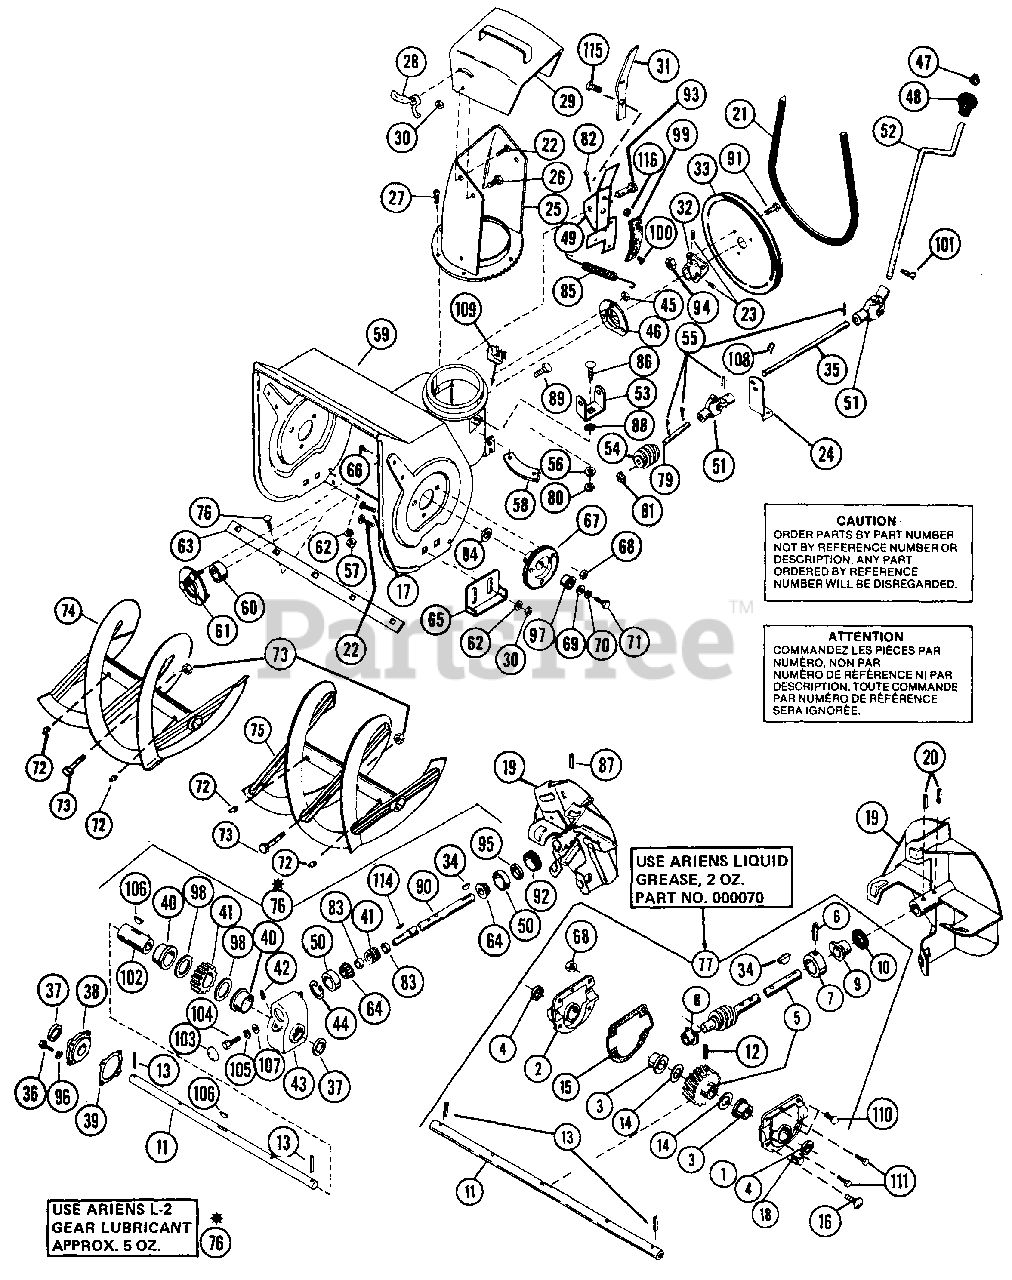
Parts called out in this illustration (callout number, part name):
1	GEAR CASE HALF L H
2	GEAR CASE HALF R H
3	BSHG-FLG1.000X1.12X.62X1.50BR
4	SEAL 1.000X1.312X.150
5	WORM SHAFT & GEAR ASSY
6	PIN-GRV .188X1.25 TP A
7	THRUST COLLAR
8	BSHG-FLG .500X.750X.750X1.000
9	BSHG-FLG .750X1.000X.750X1.250
10	O-RING .250X.943X.103
11	SHAFT, RAKE - 24"
12	PIN-GRV .313X1.44 TP C
13	PIN-ROLL .188X1.50
14	WSHR-HRD-THRS 1.007X1.542X.062
15	GASKET
16	BLT-RDHDSQNK .25-20X.88 PL
17	NOT USED ON THIS MODEL
18	BLT-SCRHFWH .38-16X.50 PL
19	FAN - 12"
20	PIN-ROLL .250X1.75
21	V-BELT, 4L-RAW EDGE
22	BLT-RDHDSQNK .38-16X.75 SHT PL
23	SCR-SET .32-18X.38 SKHCUPNL OH
24	CHUTE CRANK BRACKET
25	DISCHARGE CHUTE
26	BLT-HEX .38-16X.75 PL GR2
27	SCR-TAP 10-24X.375 HWH PL TR
28	WING NUT
29	SERVICE DEFLECTOR ASSM
30	NUT-LK-CTR .375-16 GR A PL
31	NOT USED ON THIS MODEL
33	PLY-V 9.0 X 1.25 3BLT
34	KEY-WDRF .188X.875X.375 SAE11
36	NOT USED ON THIS MODEL
37	NOT USED ON THIS MODEL
38	NOT USED ON THIS MODEL
39	NOT USED ON THIS MODEL
40	NOT USED ON THIS MODEL
41	NOT USED ON THIS MODEL
42	NOT USED ON THIS MODEL
43	NOT USED ON THIS MODEL
44	NOT USED ON THIS MODEL
45	NUT-LK-CTR .250-20 PL
46	BEARING FLANGE
47	CAP, 3/8 ROD YWZC
49	BRAKE ARM ASSEMBLY
50	NOT USED ON THIS MODEL
51	UNIVERSAL JOINT ASSY
52	CHUTE CONTROL CRANK
53	WORM CLEVIS
54	WORM GEAR L. H.
55	PIN-ROLL .125X.75
56	WSHR-LK .313X.062
57	NUT-LK .312-18 GR A PL
58	CHUTE CLAMP
59	BLOWER HOUSING W/DECALS
60	BRG-BALL .750X1.750X.50
61	BEARING FLANGE
62	WSHR-FL-STL .38X.875X.083 PL
63	SCRAPER BLADE 24"
64	NOT USED ON THIS MODEL
65	RUNNER
66	BLT-SERNK SL .25-20X.50 PL
67	BEARING SUPPORT
68	NUT-LK-FLG .250-20 PL
69	WSHR-FL-STL .511X1.441X.125 PL
70	WSHR-LK .500X.151 HVY PL
71	BLT-HEX .50-13X1.00 PL GR2
72	SPIN DRIVE ZERK FITTING
73	SHEAR BOLT SERVICE ASSEMBLY
74	RAKE, RIGHT-24"(1ID X 14.75OD)
75	RAKE, LEFT-24"(1"ID X 14.75OD)
76	NOT USED ON THIS MODEL
77	GEAR CASE - 24" - ALUMINUM
79	WORM SHAFT
80	NUT-HEX .312-18
81	WAVE WASHER .406X.750X.063FH
82	PIN-HAIR INT .06X.18X.77
83	NOT USED ON THIS MODEL
84	WSHR-FL-STL 1.010X1.505X.062PL
85	SG-TENS .062X.56X8.0 WLD 11
86	BLT-RDHDSQNK .31-18X.75 GR5 PL
87	NOT USED ON THIS MODEL
88	WSHR-LK-EXT .313X.030 PL
89	BLT-SCRHFWH .38-16X.75 PL
90	NOT USED ON THIS MODEL
91	BLT-SERRDHD SL .31-18X.87 PL
92	NOT USED ON THIS MODEL
93	CLEVIS PIN
94	NUT-FLG. .312-18 PL
95	NOT USED ON THIS MODEL
96	NOT USED ON THIS MODEL
97	BSHG-FLG 1.000X1.12X.62X1.50BR
98	NOT USED ON THIS MODEL
99	BRAKE LINING
100	RVT-TBLR .187X.375 OH ST PL
101	PIN-HAIR INT .08X.38X1.42 YWZC
102	NOT USED ON THIS MODEL
103	NOT USED ON THIS MODEL
104	NOT USED ON THIS MODEL
105	NOT USED ON THIS MODEL
106	NOT USED ON THIS MODEL
107	NOT USED ON THIS MODEL
108	PIN-HAIR INT .08X.38X1.42 YWZC
109	NUT-RETNR .38-16 TINRMAN
110	BLT-RDHDSQNK .25-20X1.25 GR5PL
111	SCR-TAP 10-24X.75 HWH PL TR
112	BLT-RDHDSQNK .312-18X.62 PL
114	NOT USED ON THIS MODEL
115	NOT USED ON THIS MODEL
116	NOT USED ON THIS MODEL
